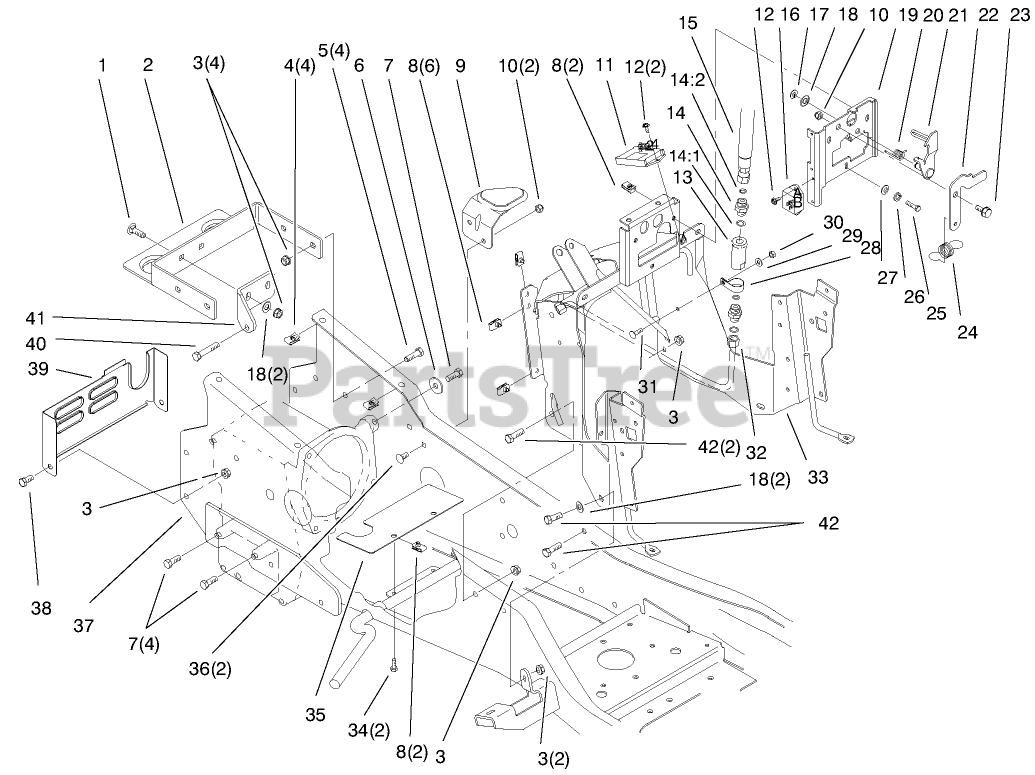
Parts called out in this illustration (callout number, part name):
1	BOLT-CARR
2	SUPPORT-GAS TANK
3	NUT-LOCK, NI
4	NUT-U
5	SCREW-HH
6	WASHER
7	SCREW-HH, LOCK
9	SUPPORT-TANK, FUEL
10	NUT-LOCK, NI
11	MODULE - DIESEL
12	SCREW
13	FILTER-SCREEN, HYD
14:1	O-RING
14:2	O-RING
15	HOSE ASM
16	MODULE - CRUISE
17	RING-RETAINING
18	WASHER-FLAT
19	BRACKET-LATCH
20	SPRING-LEVER, LATCH
22	LATCH-LEVER, TENSION
23	BOLT-SHOULDER,HFH
24	SPRING-LEVER, LATCH
25	SCREW-HH
26	WASHER-LOCK
27	WASHER-FLAT
28	CLAMP-R
29	WASHER-FLAT
30	NUT-LOCK, NI
31	BOLT-CARR
32	TUBE-HYD
33	WA-TOWER
34	SCREW-HH
35	BAFFLE-FAN
36	BOLT-CARR
38	SCREW-HH
39	COVER-REAR
40	SCREW-HH W/LOCTITE
41	STRAP-TORQUE
42	SCREW-HH
